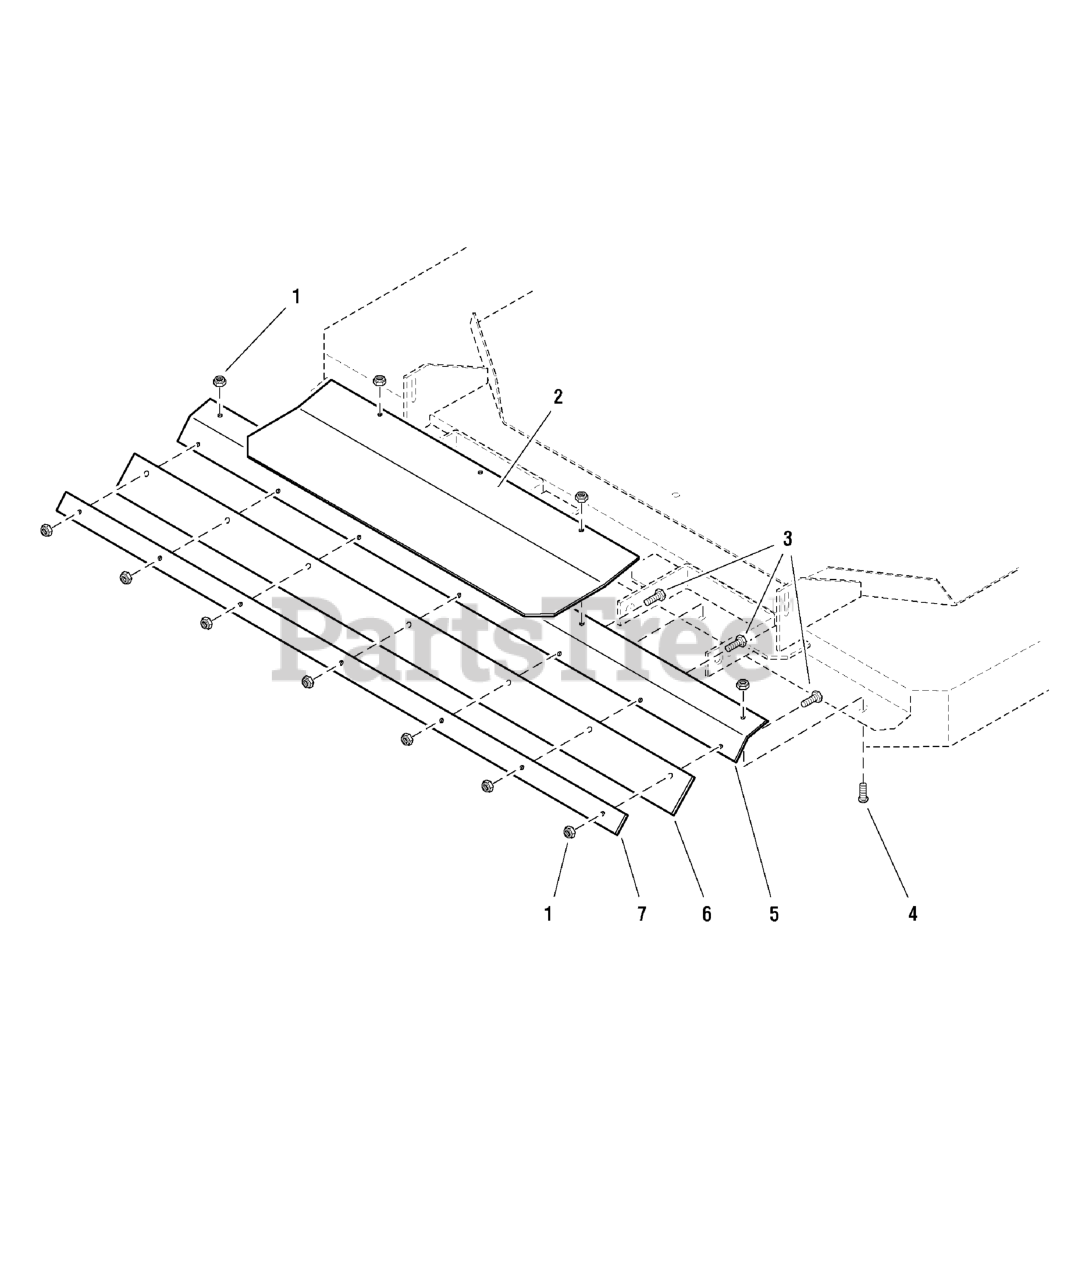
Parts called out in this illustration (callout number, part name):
1	NUT, 5/16-18 Hex Nylon Lock
3	BOLT, 5/16-18 X 1 GD5 YZ
4	CARRIAGE BOLT, 5/16-18 x 1
5	DEFECTOR MOUNT
6	RUBBER DEFLECTOR
7	RETAINING PLATE
